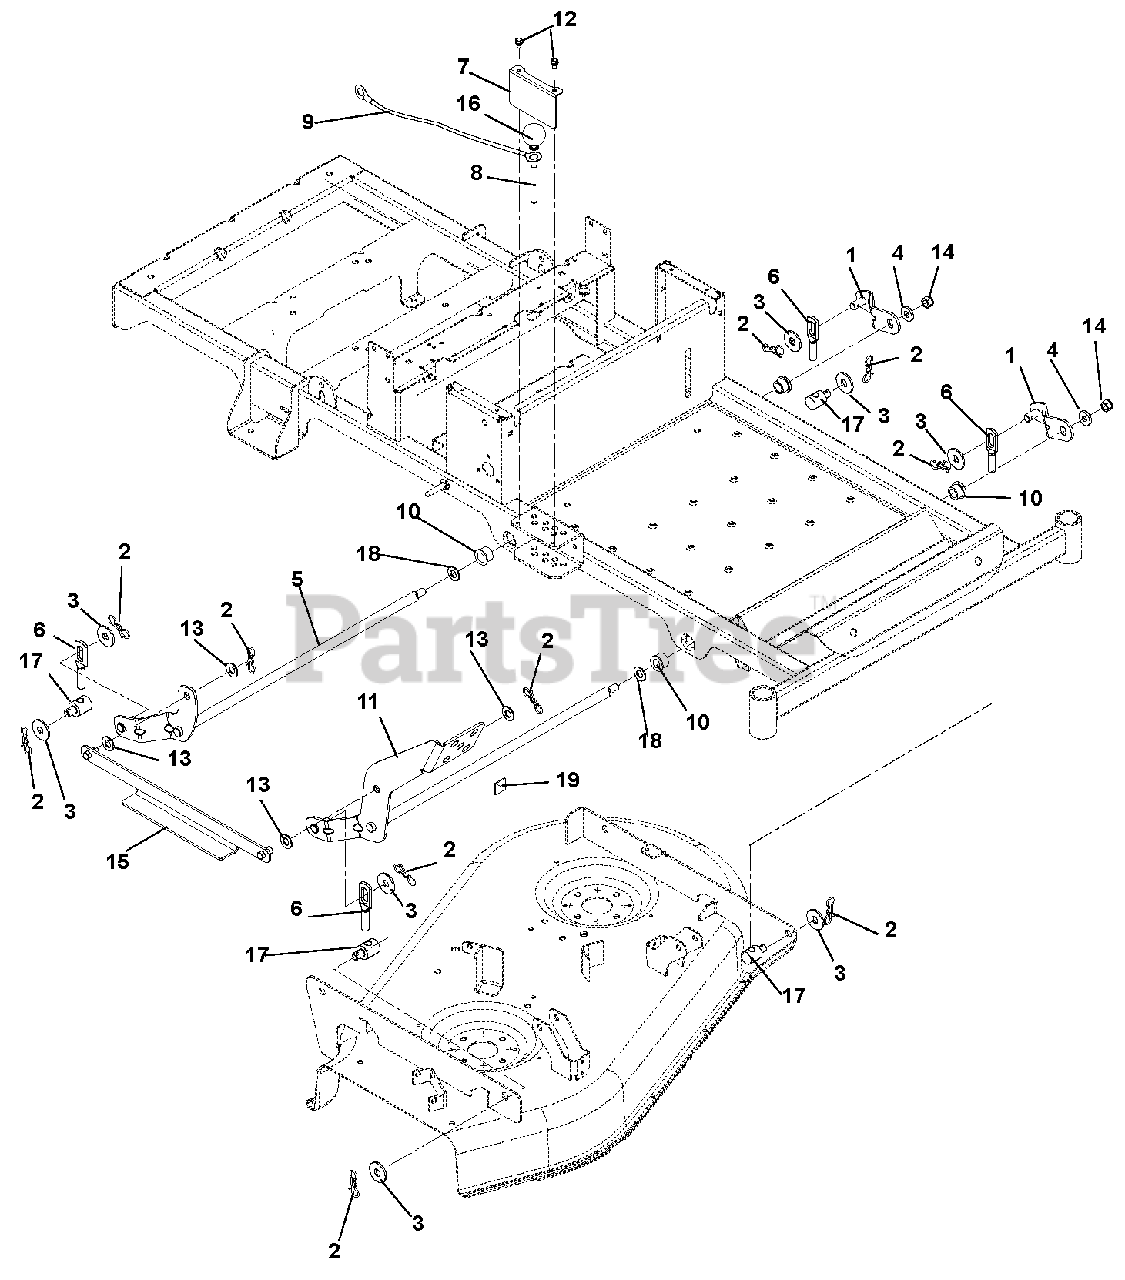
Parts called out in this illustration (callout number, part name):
1	Weldment, Lift Arm
2	Pin, Bow Tie Locking Cotter .091 x 1.875
3	Washer, Flat, Steel .511 x 1.441 x .125
4	Washer, Flat, Steel .50 x 1.25 x .160
5	Weldment, Rear Deck Lift Shaft
6	Assembly, Deck Link
7	Guard, Deck Lift
8	Pin, Deck
9	Cable, 12.0 Lanyard, Nylon
10	Bushing, Flange .627 x .879 x .469 x 1.12
11	Weldment, Deck Lift Pedal
12	Screw, Tap .25-20 x .37
13	Washer, Flat, Nylon .52 x 1.00 x .08
14	Nut, Nyloc 7/16-20
15	Weldment, Lift Link
16	Knob, Ball, Black 1.47" .375-16
17	Trunnion, .50
18	Washer, Flat Steel .656 x 1.31 x .095
19	Bumper, Rubber
